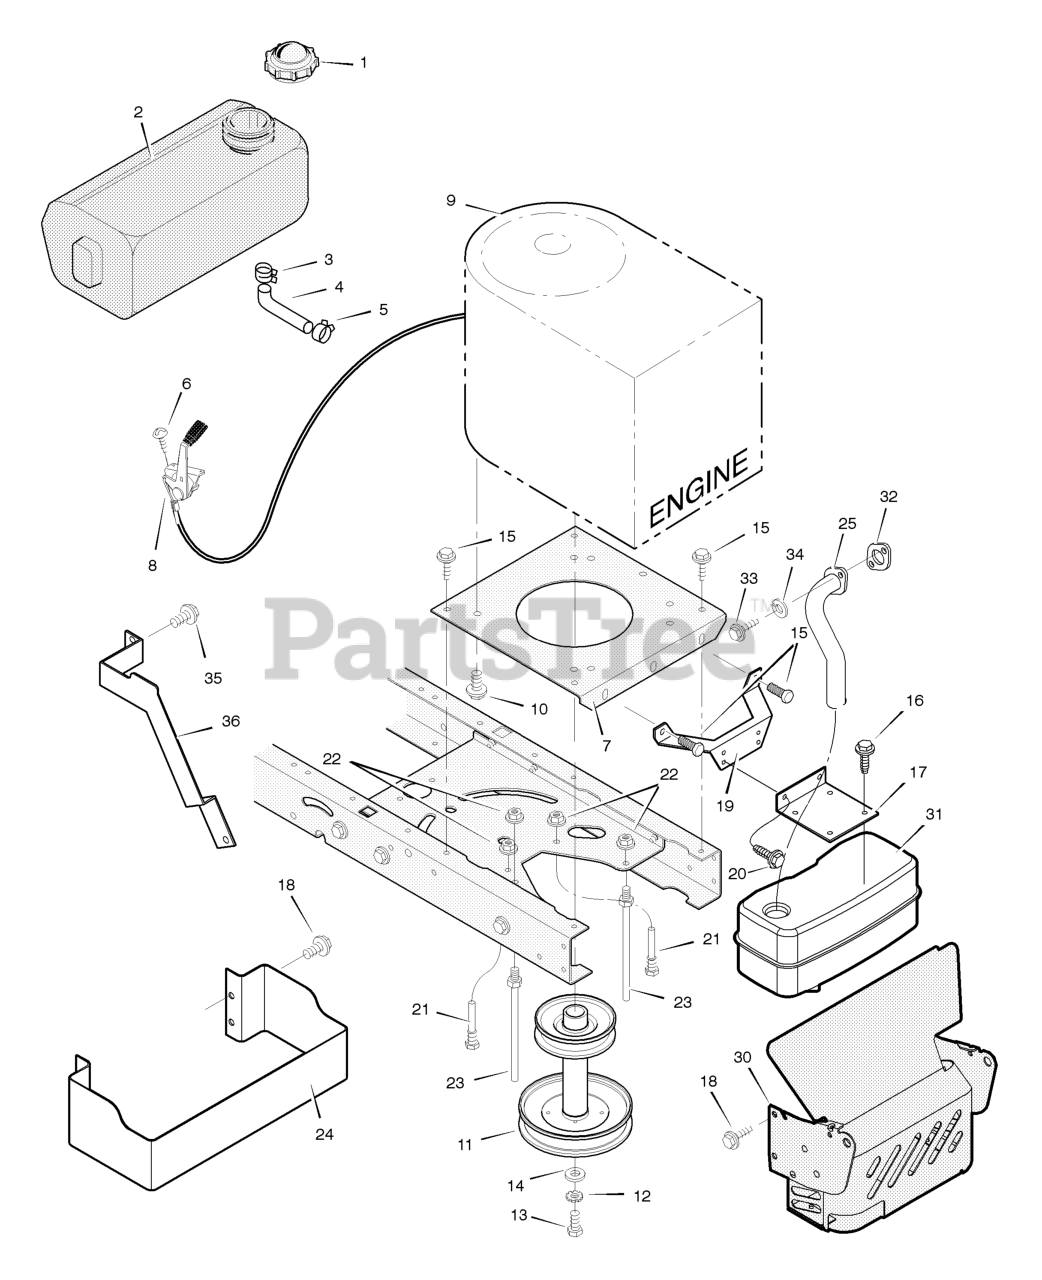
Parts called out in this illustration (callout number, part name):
1	Fuel Cap
2	TANK, Fuel 1.4 Gal.
3	Hose Clamp
4	Fuel Line (Must cut to length)
5	Hose Clamp
7	Plate, Engine
8	Throttle Control
9	Engine, Briggs & Stratton *
10	Bolt, Engine Mount
11	STACK PULLEY ASSEMBLY
12	Lockwasher
13	Bolt, Hex
17	Bracket, Muffler
19	Bracket, Muffler Mount
21	Guide, Belt
22	Nut, Flange
23	Guide, Belt
24	GUARD, Heat Shield
25	Exhaust Tube, Single
30	SHIELD, Heat
31	Muffler
32	GASKET, Exhaust
34	Washer
35	Bolt, Washer Hex Head
36	Guard, Exhaust Pipe
